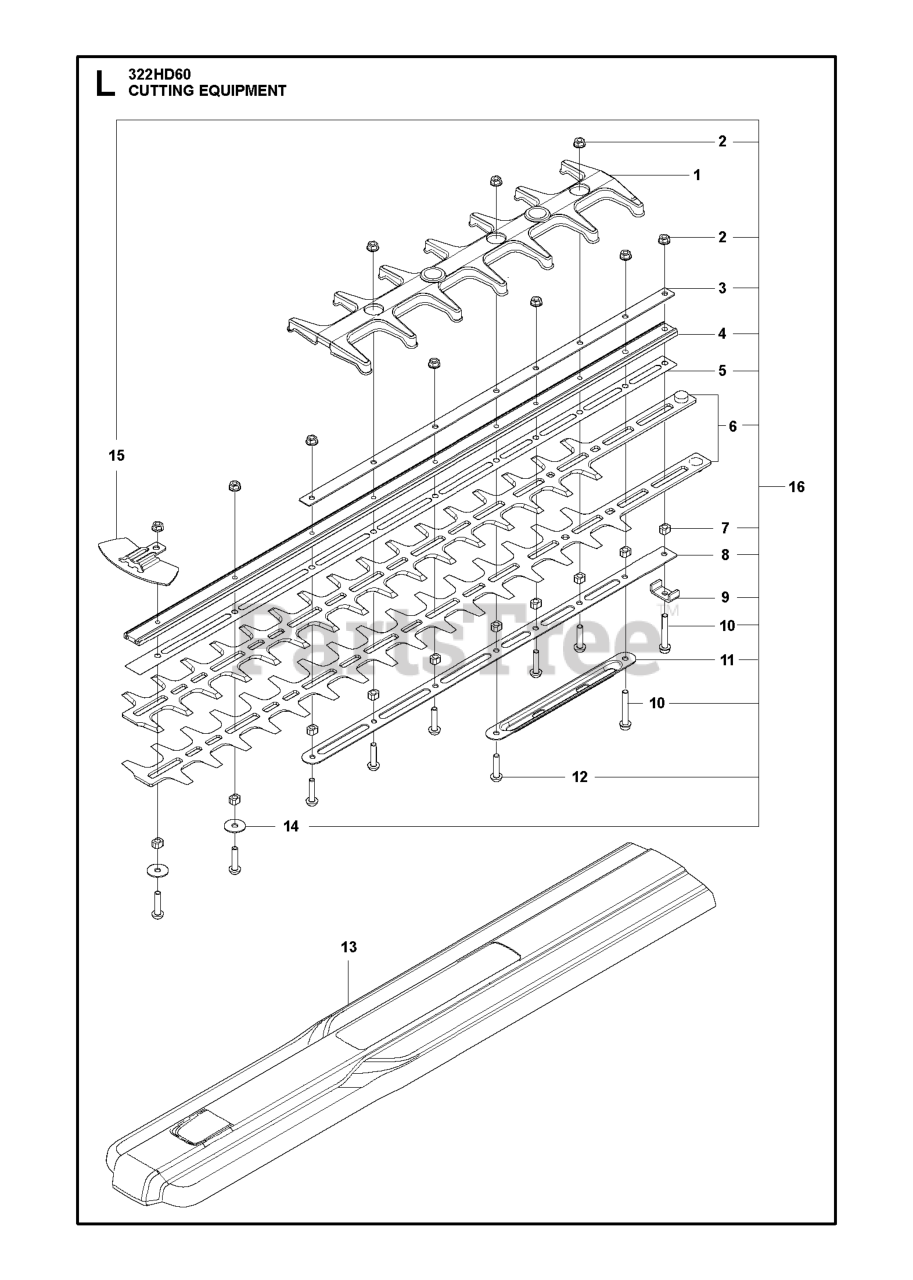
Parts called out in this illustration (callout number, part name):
1	Protection
2	NUT HEXAGON LOCK WITH FLANGE M
3	BAR PLATE UPPER
4	GUIDE BAR HD/HS60
5	WEAR PLATE
6	BLADE KIT HD60
7	SPACER CUTTING DECK
11	BAR PLATE LOWER
12	SCREW HEXALOBULAR SOCKET BUTTO
13	TRANSPORT GUARD HUSQVARNA GRE
14	WASHER PLAIN 5.5X19X1.2 ST TBO
15	PROTECTION BLADE TIP
